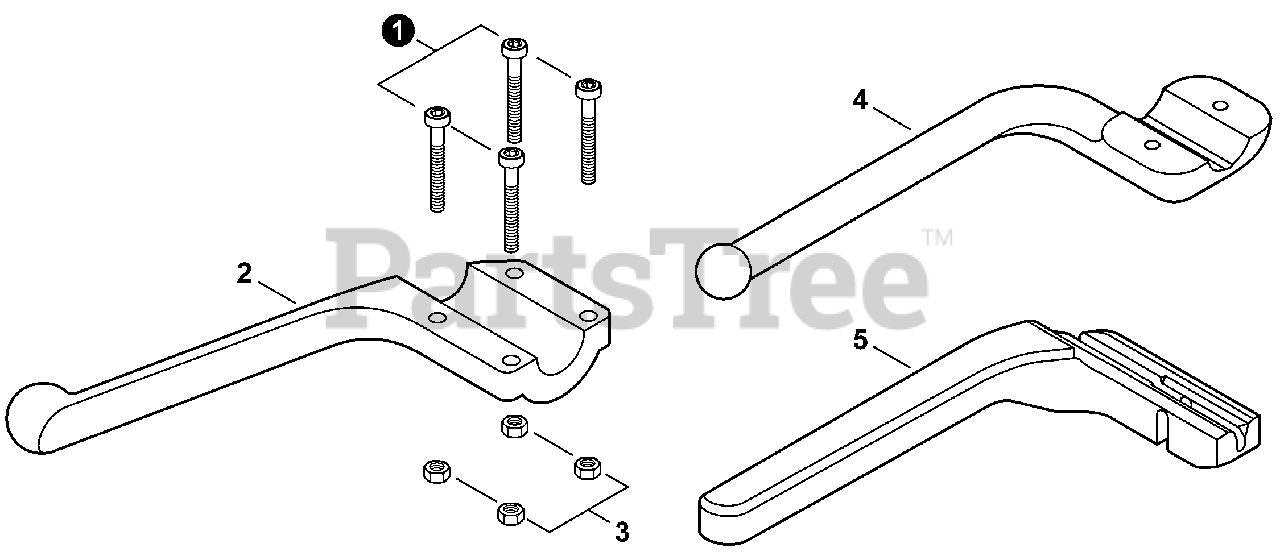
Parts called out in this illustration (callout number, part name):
1	BOLT, TORX 5×35
2	BAR, BARRIER
4	BAR, BARRIER
5	BAR, BARRIER
